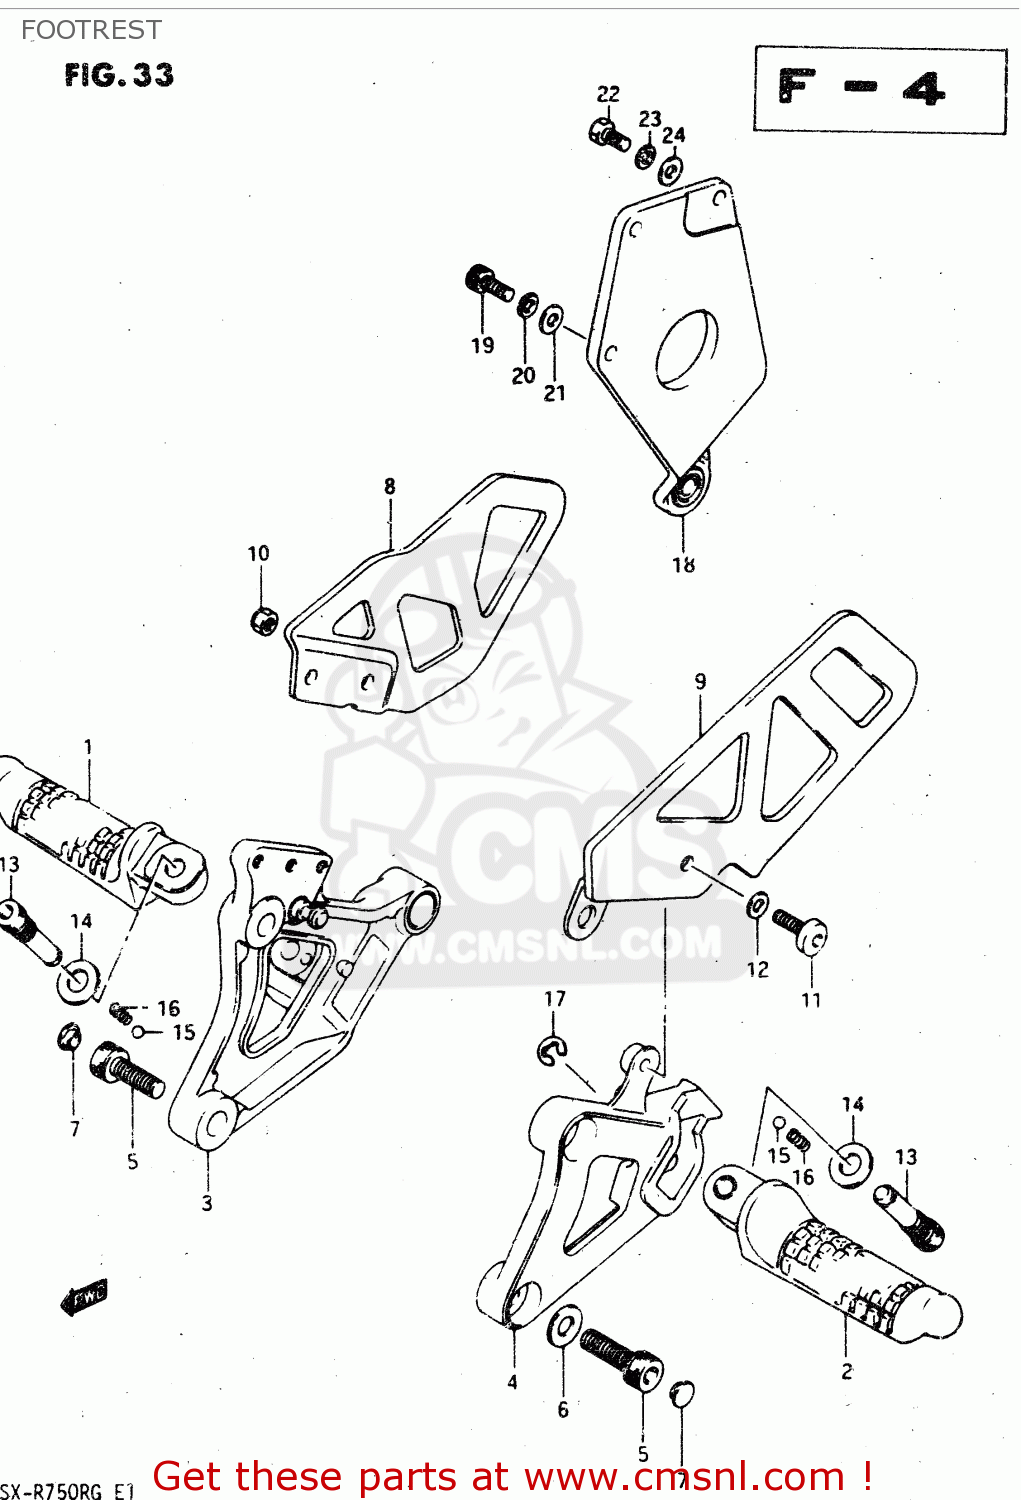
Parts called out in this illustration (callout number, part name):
1	FOOTREST ASSEMBLY,FRONT,RIGHT
2	FOOTREST ASSEMBLY,FRONT,LEFT
3	BRACKET,FOOTREST,R
4	BRACKET,FOOTREST,L
5	BOLT
6	WASHER(10.5X20X3.2)
7	CAP
8	GUARD,FRONT FOOTREST,RIGHT
9	GUARD COMP,FRONT FOOTREST
10	NUT 6MM
11	BOLT(6X18)
12	WASHER
13	BOLT,FR FOOTREST
14	PLATE, SPRING STOP
15	BALL
16	SPRING
17	E RING 6MM
18	BRACKET COMP,MUFFLER
19	BOLT
20	WASHER,LOCK
21	WASHER 6MM
22	BOLT
23	WASHER,LOCK
24	WASHER
